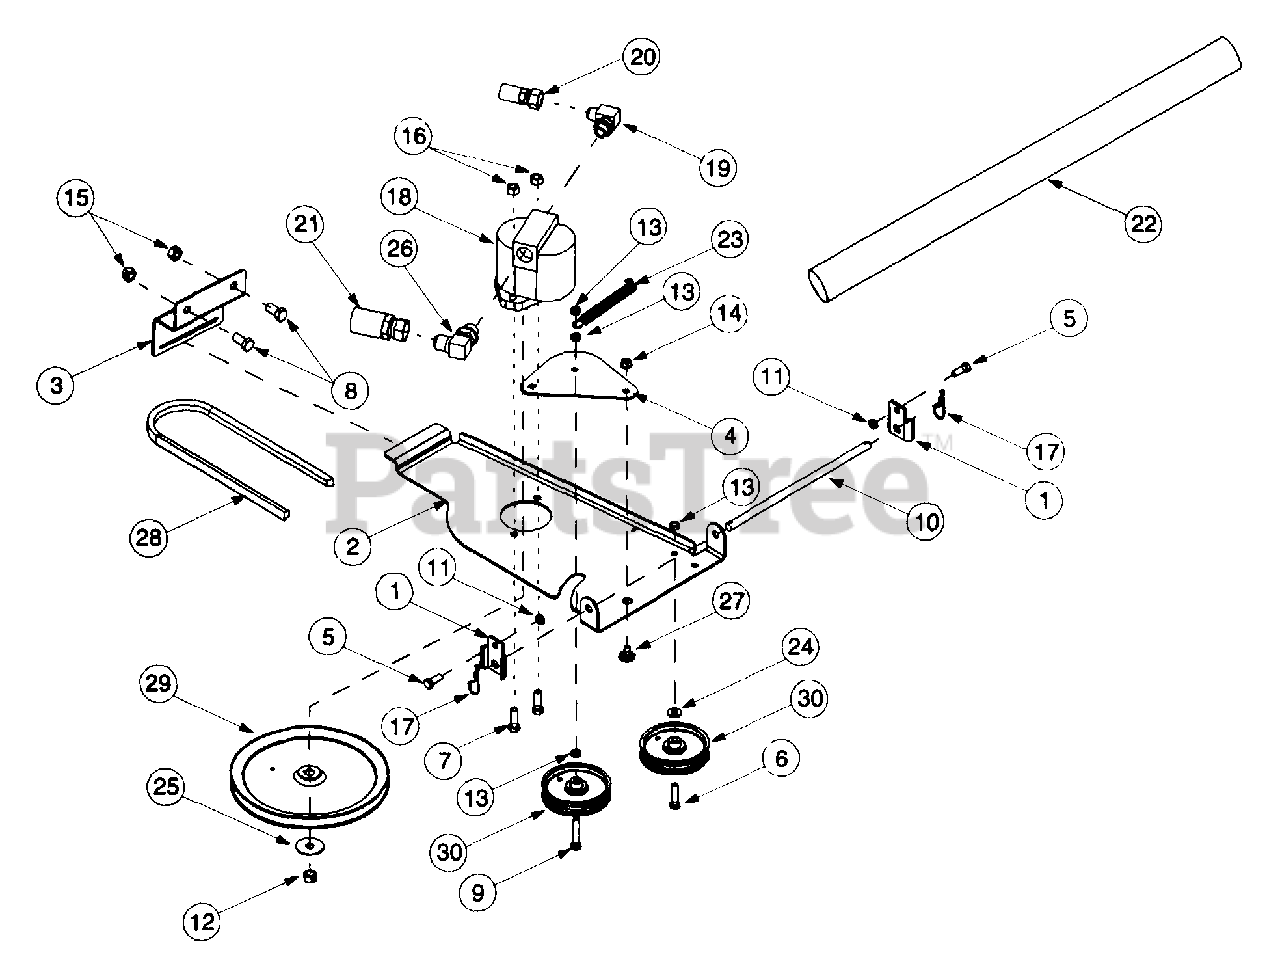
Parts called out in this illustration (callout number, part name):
1	Frame Mounting Bracket
2	Hyd. Pump Mounting Bracket
3	Rear Frame Bracket
5	Hex Cap Screw, 3/8-16 x 1.0 GR5
6	Hex Cap Screw, 3/8-16 x 1.5 GR5
7	Hex Cap Screw, 7/16-20 x 1.25 GR5
8	Hex Cap Screw, 1/2-13 x 1.0 GR5
9	Hex Cap Screw, 3/8-16 x 2.0 GR5
10	Front Hanger Rod, .5 Dia x 12.5 Lg
11	Jam Nut, Top Lock, 3/8-16
12	Hex Lock Nut, 1/2-20
13	Jam Nut, Ctr. Lock, 3/8-16
14	Flange Lock Nut, 3/8-16 GR5
15	Hex Lock Nut Ctr Lock 1/2-13
16	Hex Lock Nut, 7/16-20 GR5
17	Internal Cotter Pin
18	Eaton Hyd. Pump (26012-LAP)
19	90 degree Hydraulic Fitting, 7/8"
20	Hydraulic Hose, 7/8-14 x 57
21	Hydraulic Hose, 1 1/16-12 x 50
22	Hose Sleeve, 2.19 x 31
23	Extension Spring
24	Flat Washer, .406 x .875 x .105
25	Flat Washer, 531 x 1.75 x .090
26	90 degree Hydraulic Fitting, 1 1/16"
27	Shoulder Screw, .625 x .17, 3/8-16
28	V-Belt, A Section x 109.63
28	V-Belt, 1/2 x 117
29	Pulley, 10" Dia.
30	Idler Pulley Flat w/ Flanges
